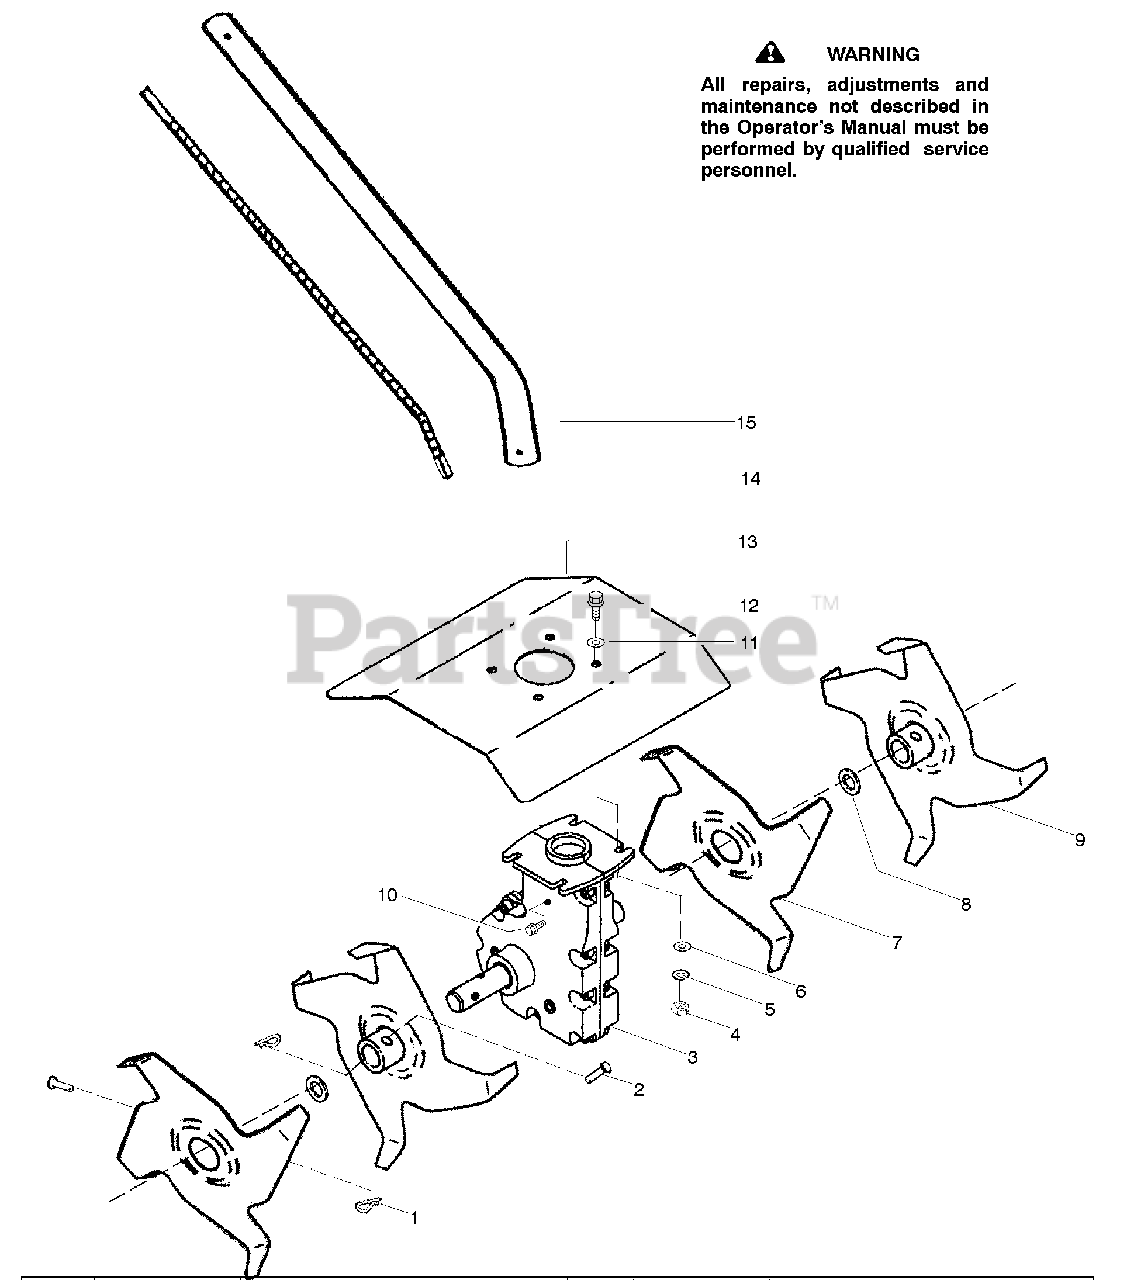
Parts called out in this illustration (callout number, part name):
1	Retainer-Hairpin
3	Kit-Gearbox
7	Tine-Right Outside/Left Inside
9	Tine-Left Outside/Right Inside
12	Bolt-Washer Head
15	Assy-Driveshaft
